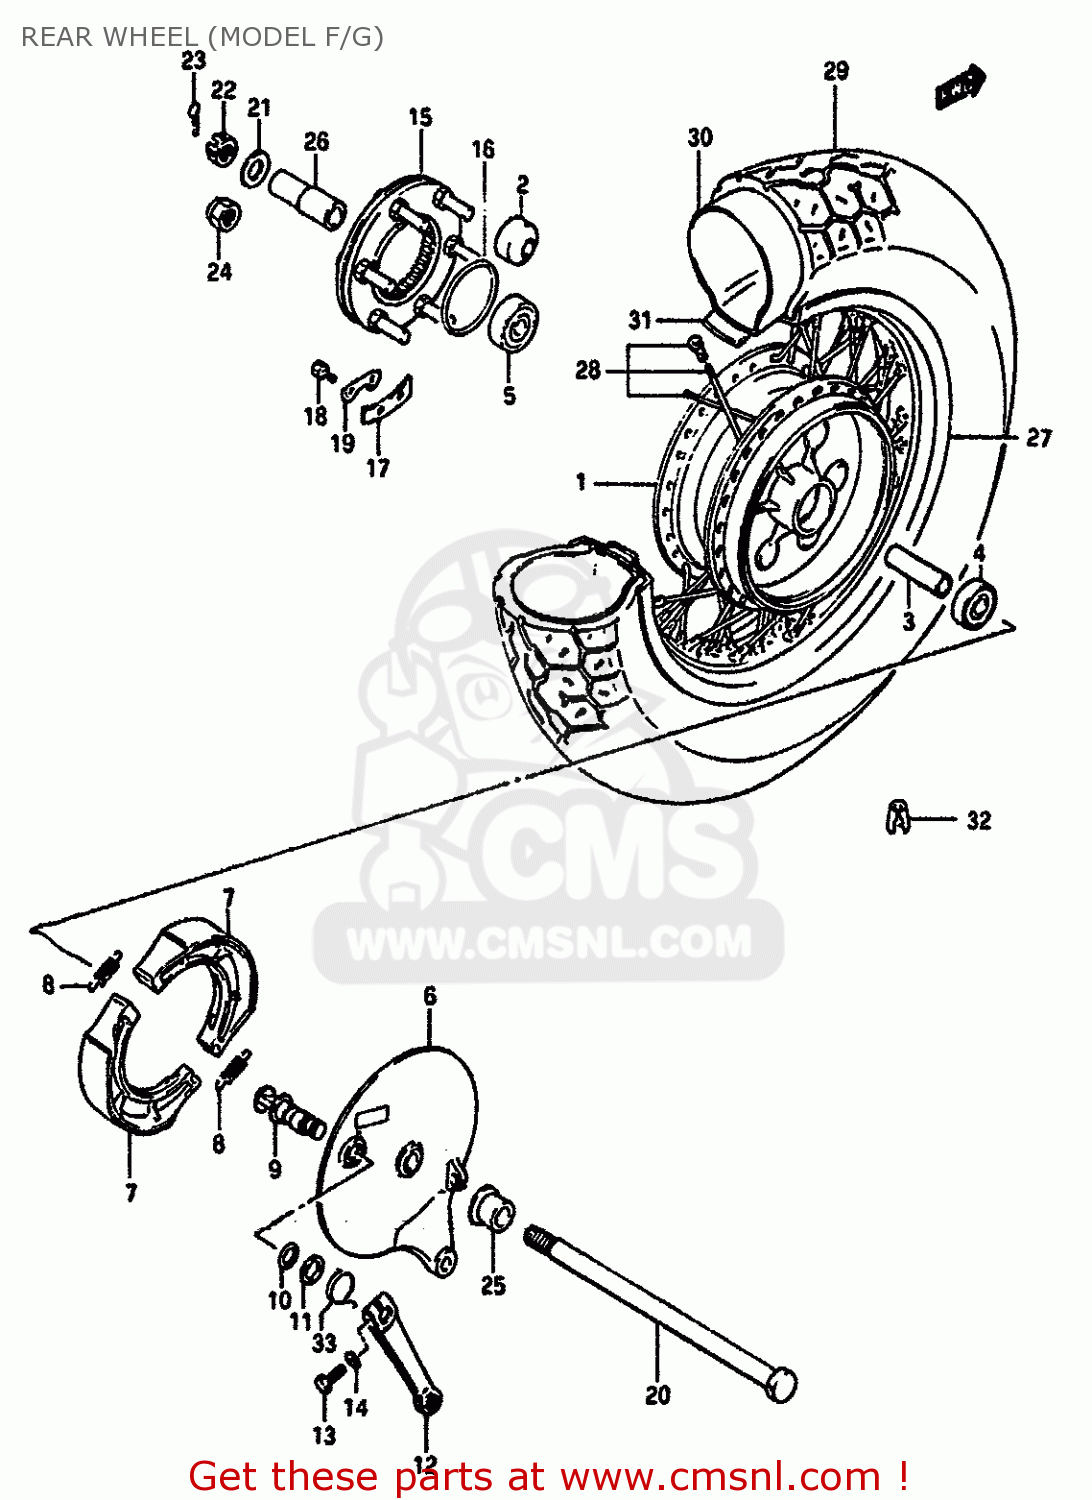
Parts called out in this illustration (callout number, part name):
1	HUB SET,REAR
2	BUSHING
3	SPACER,REAR HUB BEARING
4	BEARING
5	BEARING
6	PANEL,REAR BRAKE ANCHOR
7	SHOE SET,BRAKE (MCA)
8	SPRING,BRAKE SHOE
9	CAM,RR BRAKE
10	O-RING,BOSS
11	WASHER (15X24X1.6)
12	LEVER,RR BRAKE CAM
13	BOLT
14	WASHER,LOCK
15	JOINT ASSEMBLY,REAR HUB DRUM
16	O RING(D:2.1,ID:65)
17	WASHER,THRUST(T:1.6)
18	BOLT(6X16)
19	WASHER
20	AXLE,REAR
21	WASHER(16.5X36X3.2)
22	NUT
23	COTTER PIN
24	NUT
25	SPACER,REAR AXLE,RIGHT
26	SPACER,REAR AXLE,LEFT
27	RIM,REAR WHEEL
28	SPOKE SET,RR WHEEL
29	TIRE
30	TUBE ASSEMBLY,WHEEL,INNER
31	PROTECTOR,WHL INR TUBE
32	BALANCER,WHEEL
33	SPRING
